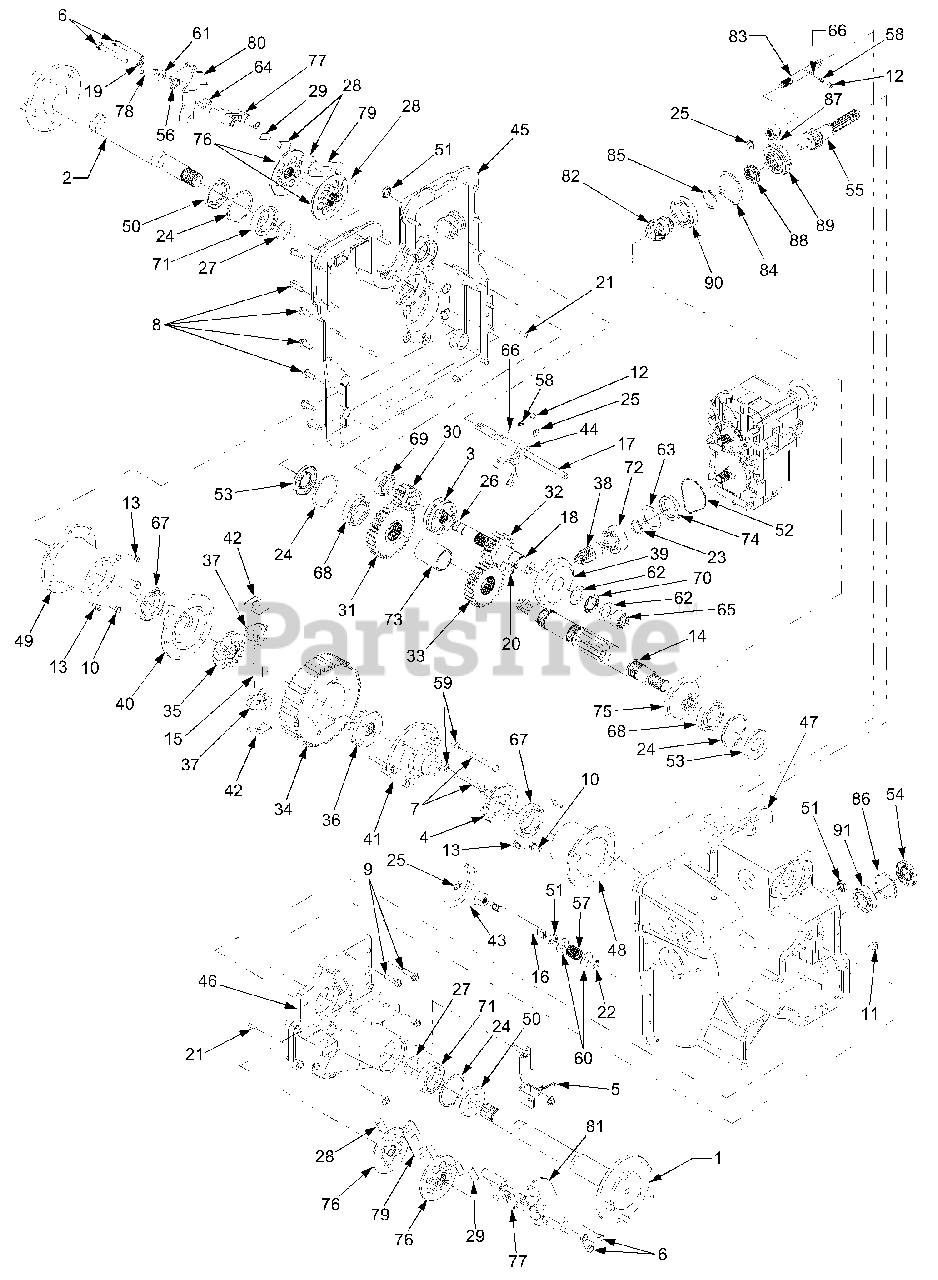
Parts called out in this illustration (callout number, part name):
1	Shaft, Axle RH
2	Shaft, Axle LH
3	Collar Assembly, Hi-Lo
4	Collar Assembly, Diff Lock
5	Bracket, Diff. Lock
6	Screw, Hex Cap, 5/16-18 x 2.75 GR5
7	Screw, Hex Cap, 5/16-18 x 2.5 GR5
8	Screw, Hex Wash. Hd. Tapp, 5/16-18 x 1.0
9	Screw, Hex Wash. Hd. Tapp, 5/16-18 x 1.25
10	Screw, Hex Cap, w/Patch 5/16-18 x .75 GR5
11	Screw, Plug, M14 x 1.5 x .827
12	Screw, Set, 5/16-18 x .375
13	Screw, Shoulder .309 x .375: 1/4-20
14	Shaft, Output, 11T
15	Shaft, Cross, .625 x 3.95
16	Shaft, Diff. Lock Actuator
17	Shaft, Hi-Lo Actuator
18	Shaft, Drive
19	Nut, Hex Insert Lock, 5/16-24
20	Key, Woodruff, 1/4 x 3/4
21	Pin, Dowel, .25 x .75
22	Ring, Retaining
23	Ring, Snap
24	Ring, Retaining
25	Clip, Rotor
26	Ring, Retaining
27	Ring, Retaining
28	Pad, Brake
29	Plate, Brake Puck
30	Gear, Spur, 12T
31	Gear, Spur, 34T
32	Gear, Spur, 19T
33	Gear, Spur, 27T
34	Gear, Spur, 56T
35	Gear, Bevel, 16T
36	Gear, Bevel, 16T Lock
37	Gear, Bevel, 10T Diff
38	Gear, Spiral Bevel, 13T
39	Gear, Spiral Bevel, 54T
40	Cover, Differential
41	Cover, Differential Lock
42	Block, Thrust
43	Actuator Arm, Diff. Lock
44	Yoke, Shift, Hi-Lo
45	Cover, Trans. Large
46	Cover, Trans. Small
47	Housing, Trans
48	Housing, Axle Inner - RH
49	Housing, Axle Inner - LH
50	Seal, Oil
51	Seal, Oil
52	Seal, Gland
53	Seal, Oil
54	Seal, Oil
55	Shaft, 4WD
56	Spring, Torsion
57	Spring, Compression, .845 x 1.0
58	Spring, Compression, .24 x .563
59	Washer, Lock, 5/16
60	Washer, Flat, .56 x 1.0 x .04
61	Washer, Flat, .343 x .88 x .062
62	Washer, Thrust
63	Washer, Flat, 1.52 x 2.0 x .030
64	Pin, Brake Actuating
65	Bearing, Needle
66	Ball, Detent
67	Bearing, Ball
68	Bearing, Ball
69	Bearing, Ball
70	Bearing, Needle Thrust
71	Bearing, Ball
72	Bearing, Ball
73	Spacer, 1.51 x 1.75 x 2.41
74	Spacer, 1.515 x 2.039 x .335
75	Gear, Spiral Bevel, 36T
76	Disc, Brake
77	Yoke, Brake
78	Bracket, Brake Anti Rotation
79	Plate, Puck Retainer
80	Arm, Brake Actuator - LH
81	Arm, Brake Actuator - RH
82	Gear Assembly w/Bearings
83	Shaft, 4WD Actuator
84	Ring, Retaining
85	Ring, Retaining
86	Ring, Retaining
87	Yoke, 4WD
88	Gear, Spline Coupling
89	Collar, Shift
90	Bearing, Ball
91	Bearing, Ball
